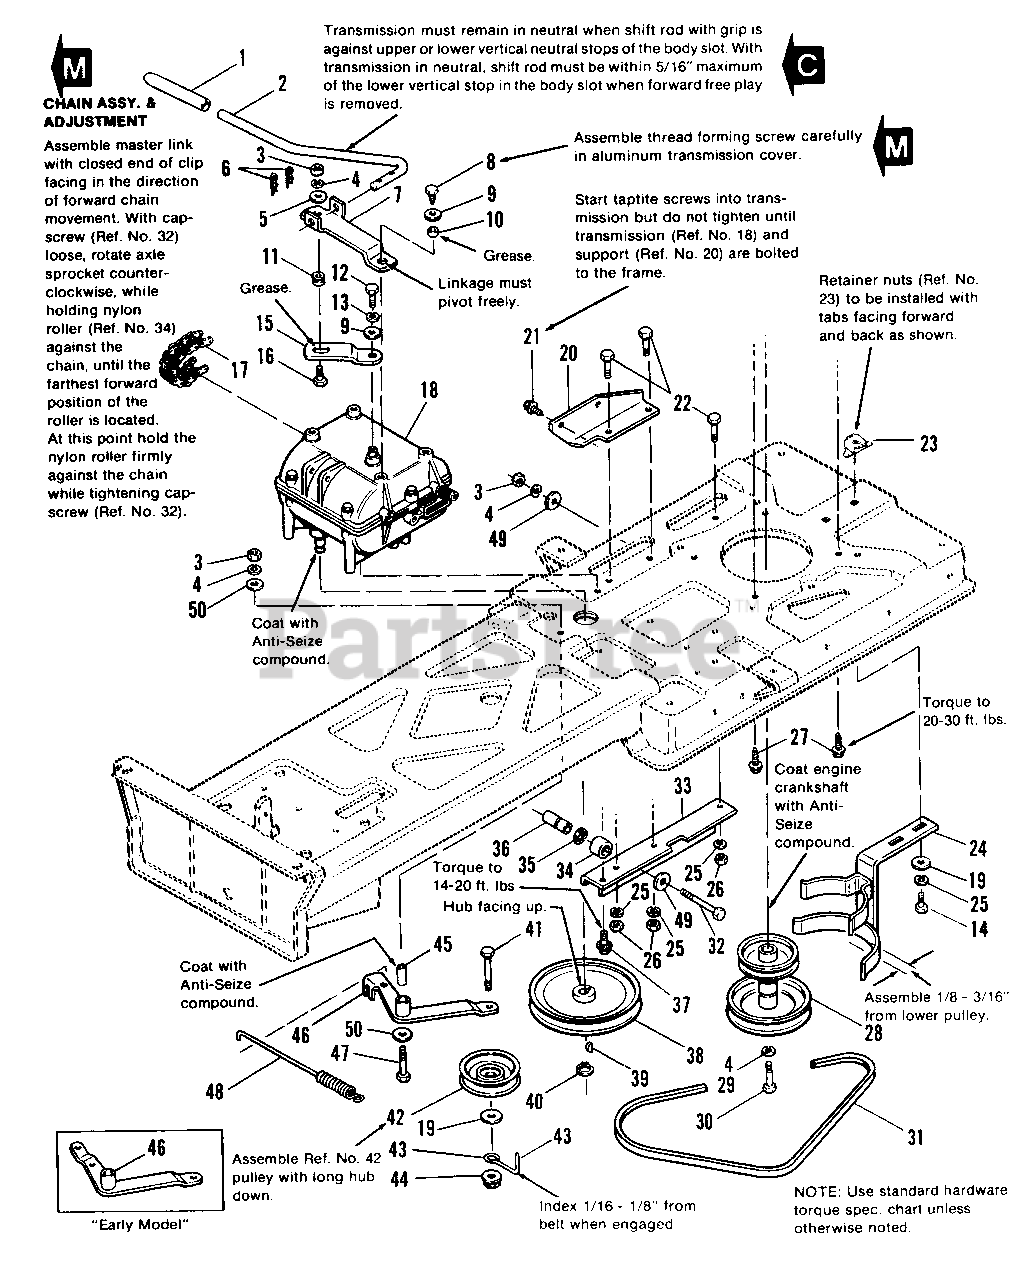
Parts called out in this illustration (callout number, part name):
1	GRIP, Handle
2	ROD, Shift
3	NUT, Hex, 3/8-16
4	LOCKWASHER, 3/8 (Qty. 3 on 8 & 10 HP)
5	WASHER, Plain, 13/32
6	CLIP, Hairpin
7	PIVOT, Shift
8	SCREW, Hex, Taptite, 5/16-18 x 3/4
9	WASHER, Plain, 1/4
12	CAPSCREW, Hex, 1/4-28 x 5/8
13	LOCKWASHER, 1/4
14	CAPSCREW, Hex 5/16-18 x 1
15	LINK, Shift
16	CAPSCREW, Hex, 3/8-16 x 1
17	CHAIN, Roller
19	WASHER, Plain, 5/16
20	SUPPORT, Transmission
21	SCREW, Hex, Taptite, 1/4-20 x 5/8
22	CAPSCREW, Hex, 5/16-18 x 3/4
23	NUT, Retainer, 5/16-18
24	BELT STOP ASSY.
25	LOCKWASHER, 5/16
26	NUT, Hex, 5/16-18
27	SCREW, Hex, Taptite, 3/8-16 x 1-1/4
28	ENGINE PULLEY ASSY.
29	LOCKWASHER, 7/16 (8 & 10 HP only)
30	CAPSCREW, 7/16-20 x 1-1/2 (8 & 10 HP only)
30	CAPSCREW, 3/8-24 x 1-1/2 (5 HP only)
32	CAPSCREW, Hex, 3/8-16 x 3
33	SUPPORT, Chain
35	E-RING, Retainer
36	SPACER, Roller
37	SCREW, Hex, Whizlock 5/16-18 x 3/4
38	PULLEY ASSY.
39	KEY, Woodruff, #9
40	RING, Retaining
41	CAPSCREW, Hex, 3/8-16 x 1-3/4
42	PULLEY, Idler
44	LOCKWASHER, Hex, Flange, 3/8-16
46	CLUTCH ARM ASSY.
47	CAPSCREW, Hex, 3/8-16 x 2
49	WASHER, Plain, 13/32 x 1 x 10 Ga.
50	WASHER, Plain, 3/8
